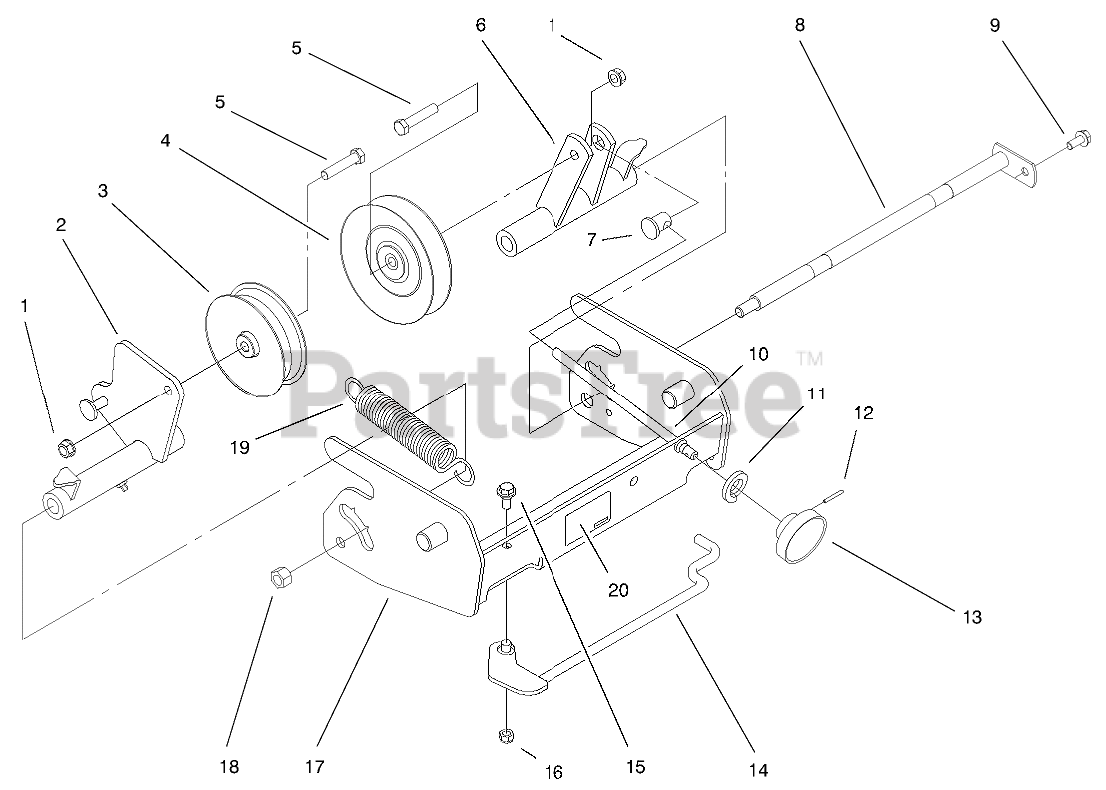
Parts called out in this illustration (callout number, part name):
1	NUT-LOCK, NI
2	WA - IDLER ARM
3	PULLEY-IDLER
4	PULLEY-IDLER
5	SCREW-HH
6	Idler Lever
7	FERRULE-ADJUSTER
8	ROD-PIVOT
9	SCREW-HWHTF
10	ROD-TENSION
11	WASHER-SPRING
12	PIN-ROLL
13	KNOB-ADJUSTMENT
14	TENSIONER-IDLER
15	SCREW-SHOULDER
16	NUT-LOCK, NI
17	BOX-PULLEY
18	NUT-HEX
19	SPRING-EXTENSION
20	DECAL-BELT ROUTING
